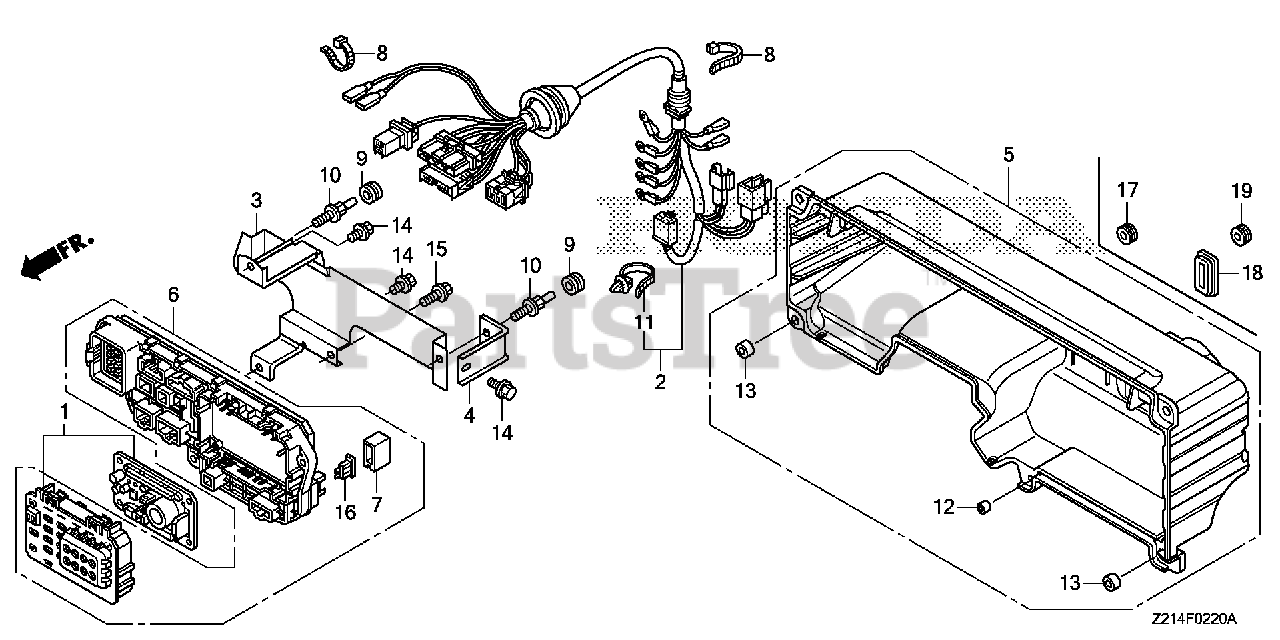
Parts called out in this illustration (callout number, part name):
1	COVER ASSY., AUTOMATIC VOLTAGE REGULATOR
2	WIRE HARNESS ASSY., GENERATOR (EM-A)
3	BRACKET, JUNCTION BOX
4	PLATE, JUNCTION BOX
5	CASE, CONTROL PANEL
6	BOX ASSY., JUNCTION
7	COVER, FUSE
8	TIE, CABLE (C)
9	GROMMET, SEAT LOCK LEVER
10	BOLT, FLANGE (6X18)
11	CLIP, HARNESS BAND (145MM) (BLACK)
12	COLLAR, CONTROL CASE
13	COLLAR, CONTROL CASE
14	BOLT, FLANGE (6X10)
15	BOLT, FLANGE (6X14)
16	FUSE, BLADE (20A)
